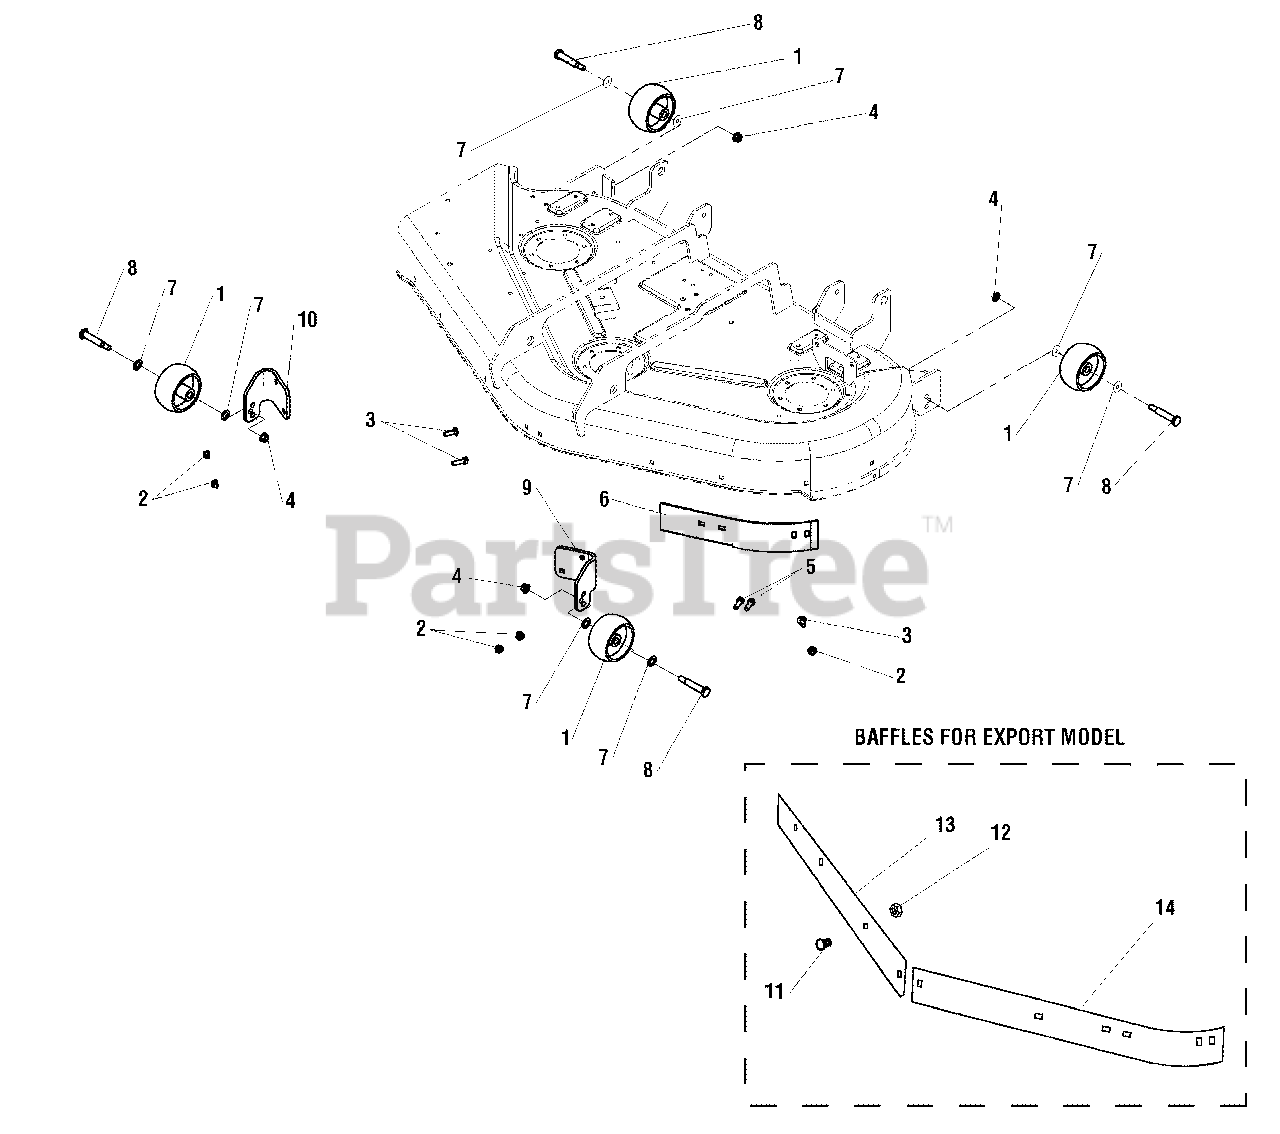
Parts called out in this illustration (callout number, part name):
1	WHEEL, 2.00 WIDE 3.88 DIA 0.531ID POLY
2	NUT, 5/16-18 HEX NYLOCK FLANGE
3	BOLT, 5/16-18 X 3/4, CARRIAGE
4	NUT, 3/8-16 HEX NYLOCK FLANGE
5	BOLT, 5/16-18 X 1, CARRIAGE
6	BAFFLE, BLOWOUT, 44" / 50" MOWERS
7	WASHER, 0500(0.51IDX0.87ODX.06THK) BLK
8	BOLT, WHEEL 3/8-16X2.781 .750 THRD YELLOW
9	BRACKET, GUAGE WHEEL, LH
10	BRACKET, GAUGE WHEEL, RH
11	BOLT, 5/16-18 X 3/4, CARRIAGE
12	NUT, 5/16-18 HEX NYLON LOCK
13	BAFFLE, BLOWOUT RH 50" MWR - BLACK
14	BAFFLE, BLOWOUT LH 50" MWR - BLACK
15	BAFFLE, FRONT, 44 / 50 MOWER
